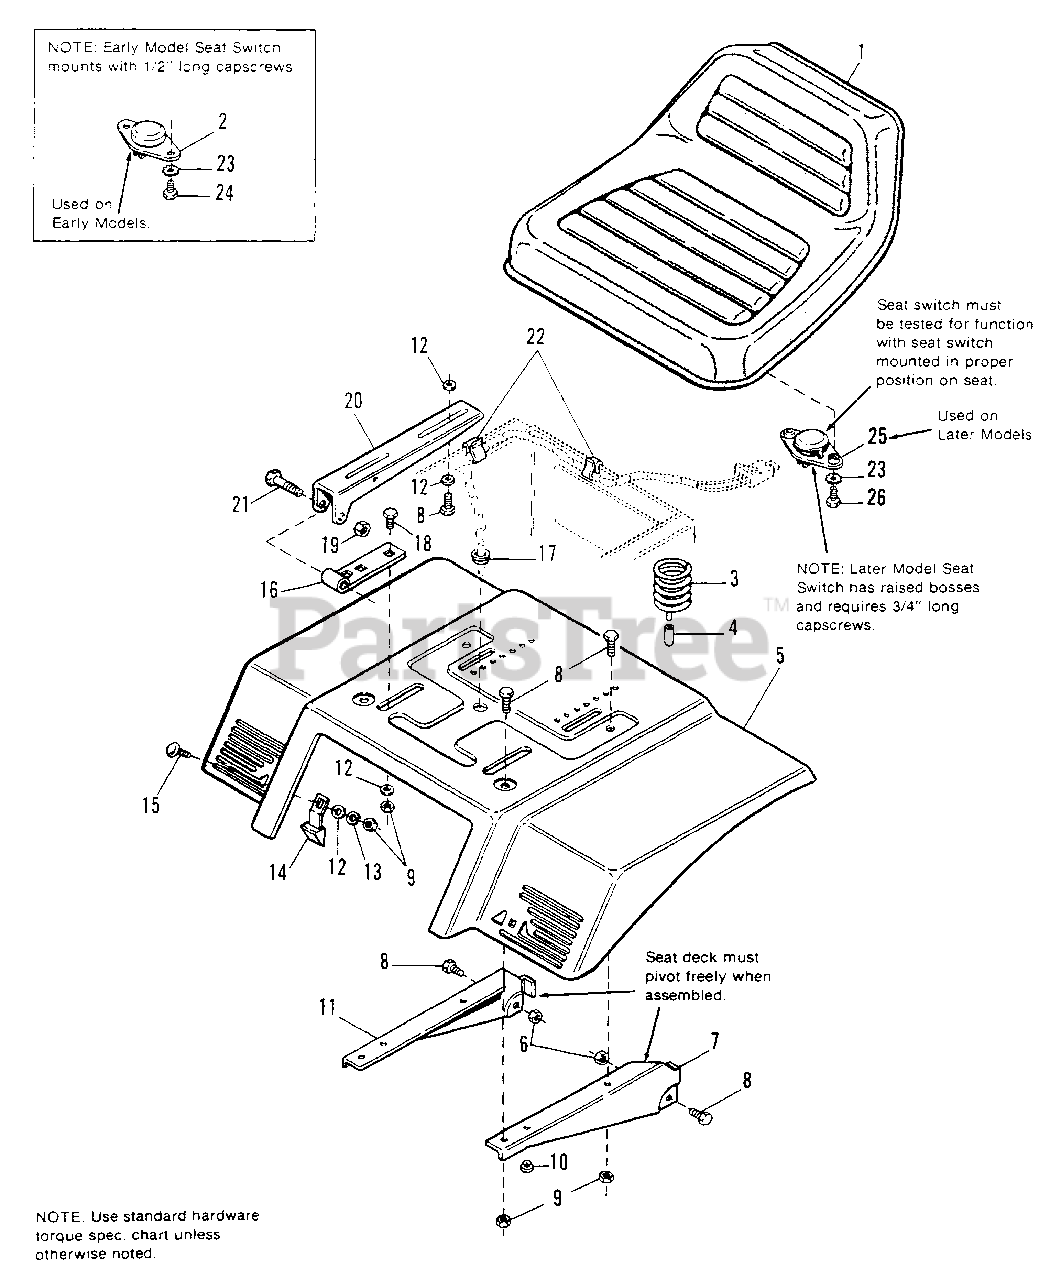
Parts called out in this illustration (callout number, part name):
2	SWITCH, Seat (Early Models)
3	SPRING, Seat
4	COVER, Wire
5	DECK, Seat
6	NUT, Lock, Hex, 5/16-18
7	SUPPORT, Seat, L.H.
8	CAPSCREW, Hex Hd., 5/16-18 x 3/4
9	NUT, Hex, 5/16-18
10	BUMPER, Plug
11	SUPPORT, Seat, R.H.
12	WASHER, 5/16
13	LOCKWASHER, 5/16
14	SEAT LATCH ASSY.
15	BOLT, Carriage. 5/16-18 x 3/4
16	HINGE, Lower
17	BUSHING, Snap
18	CAPSCREW, Hex Hd., 5/16-18 x 1
19	NUT, Hex Lock, 3/8-16
20	HINGE, Upper
21	CAPSCREW, Hex Hd., 3/8-16 x 2
23	LOCKWASHER, Ext. Tooth, 1/4
24	SCREW, Rd. Hd., 1/4-20 x 1/2 (Early Models only)
25	SWITCH, Seat (Later Models)
26	SCREW, Rd. Hd., 1/4-20 x 3/4
